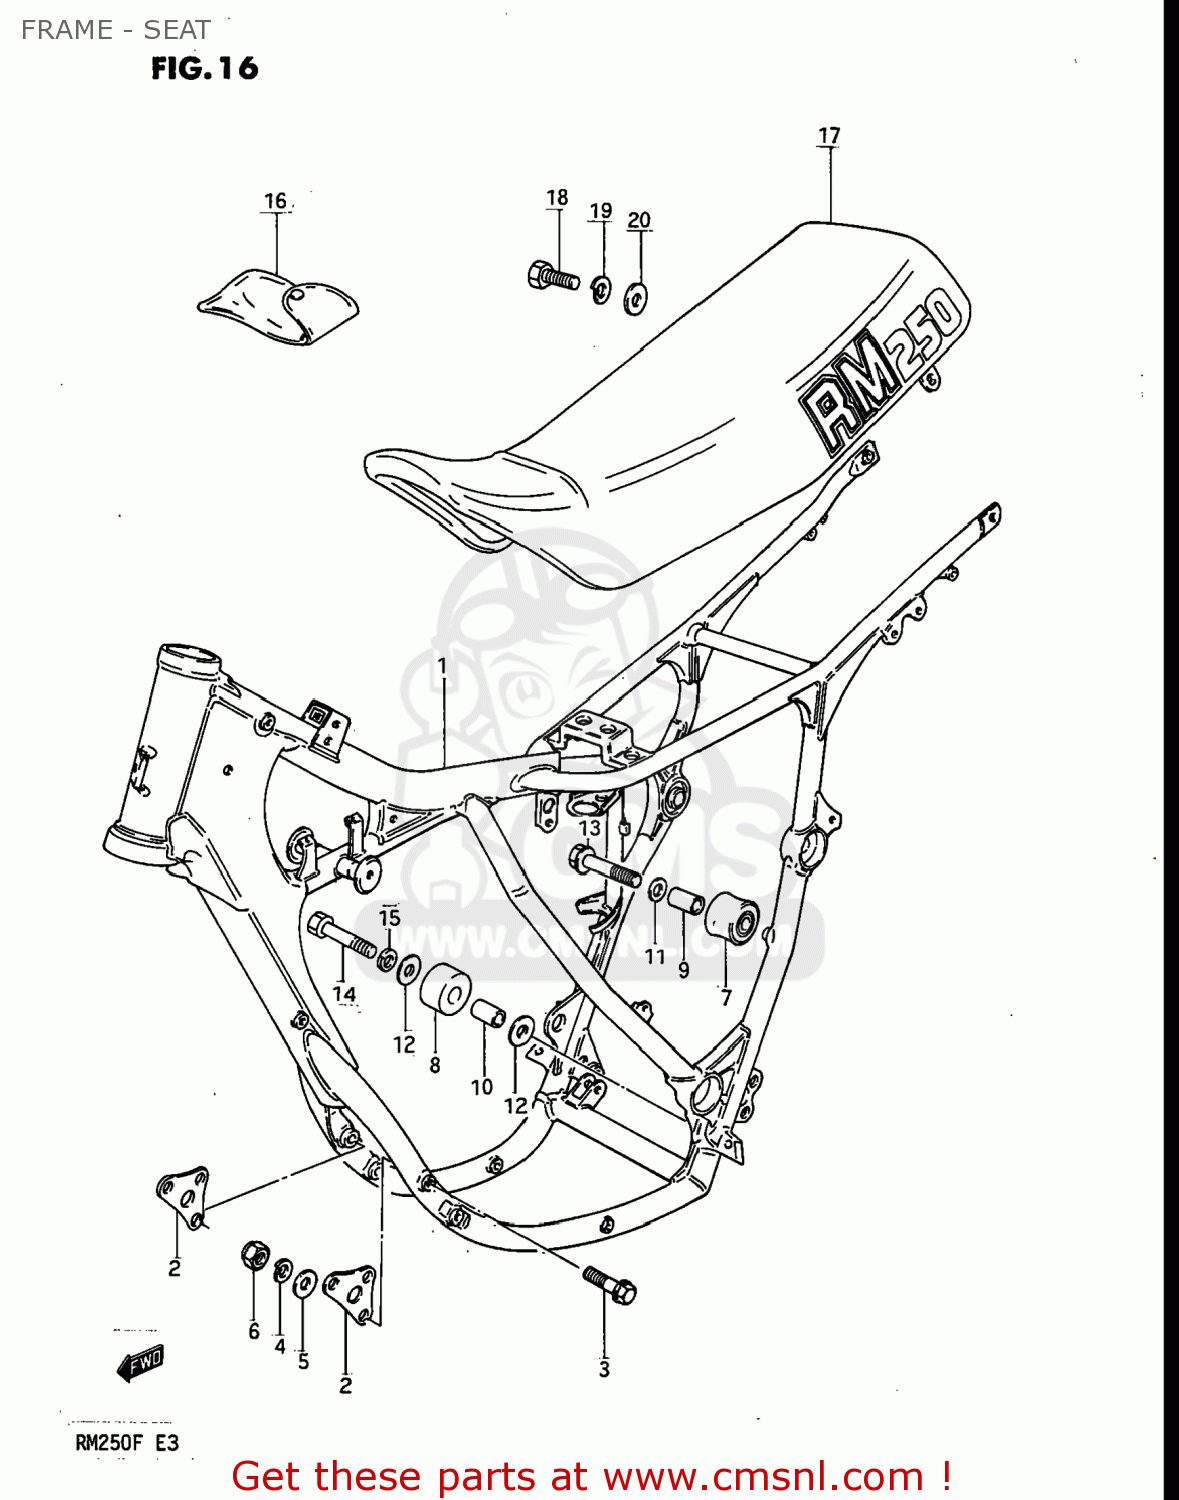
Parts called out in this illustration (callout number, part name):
1	FRAME
2	PLATE,ENGINE MOUNTING
3	BOLT 8X55
4	LOCK WASHER
5	WASHER
6	NUT
7	ROLLER,CHAIN
8	ROLLER,CHAIN LENGTH CONTROL
9	SPACER,CHAIN LENGTH ROLLER
10	SPACER(8.6X12X25.5)
11	WASHER
12	WASHER (8.5X25X1.2)
13	BOLT(8X45)
14	BOLT 8X45
15	WASHER,LOCK,8.
16	TOOL SET
17	SEAT ASSEMBLY
18	BOLT
19	LOCK WASHER
20	WASHER
